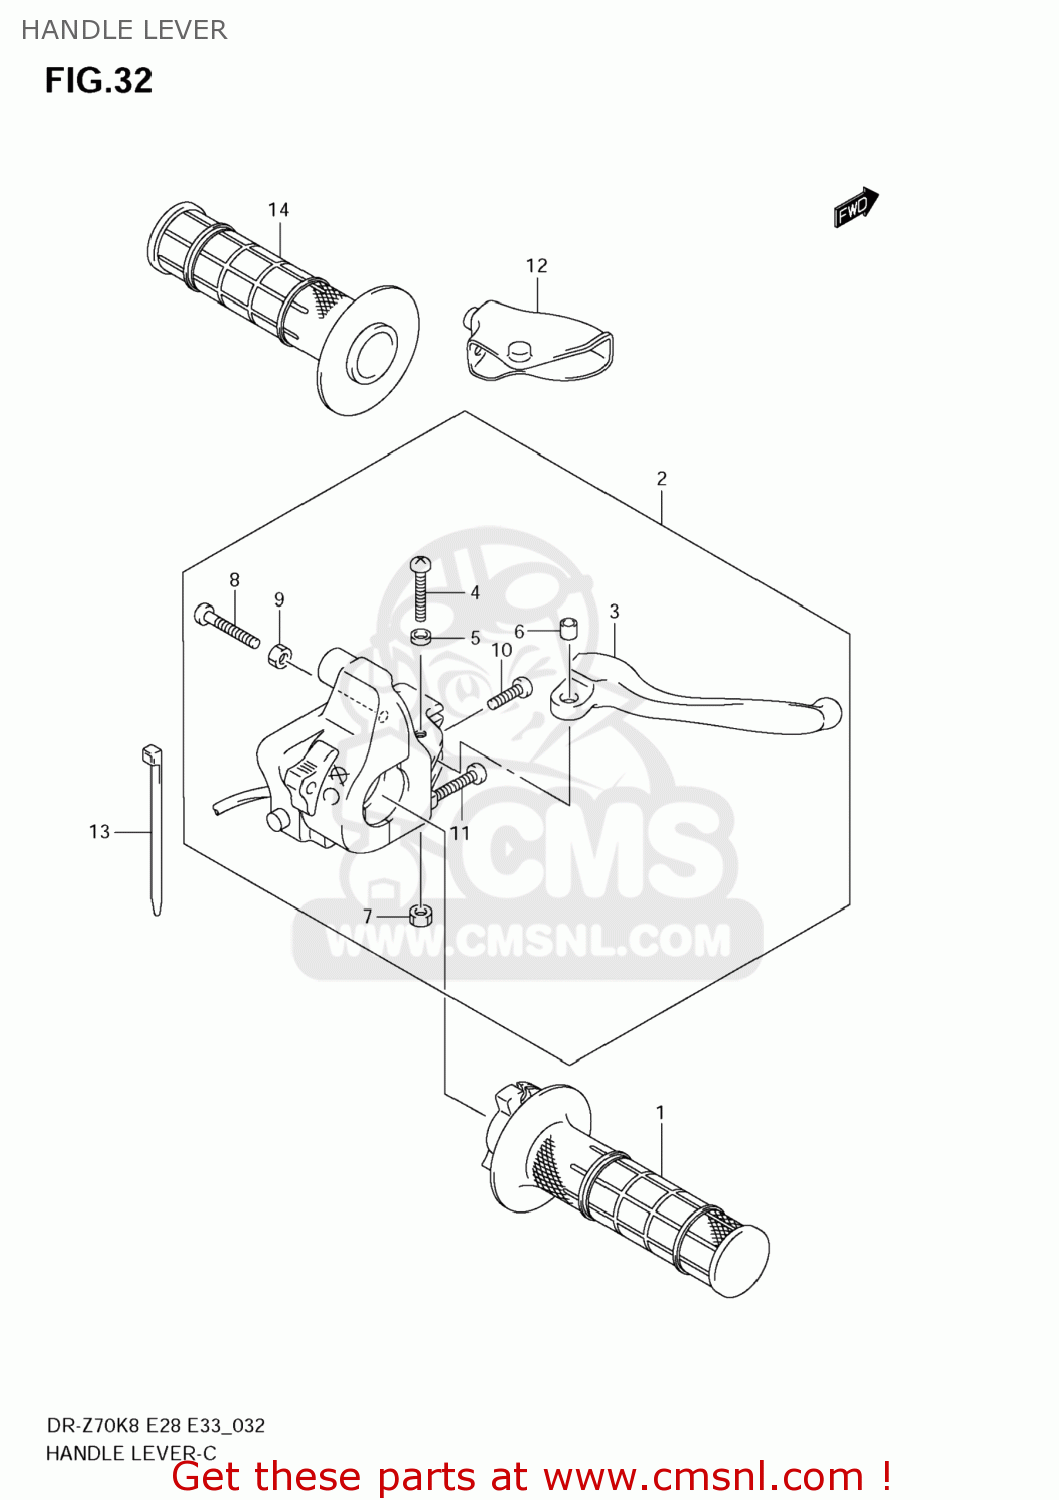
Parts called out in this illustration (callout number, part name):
1	GRIP,THROTTLE
2	LEVER ASSY,FR
3	LEVER,BRAKE
4	SCREW
5	COLLAR
6	SPACER
7	NUT
8	SCREW
9	NUT
10	SCREW
11	SCREW
12	COVER,BRAKE LEVER
13	CLAMP(L:95)
14	GRIP,L
